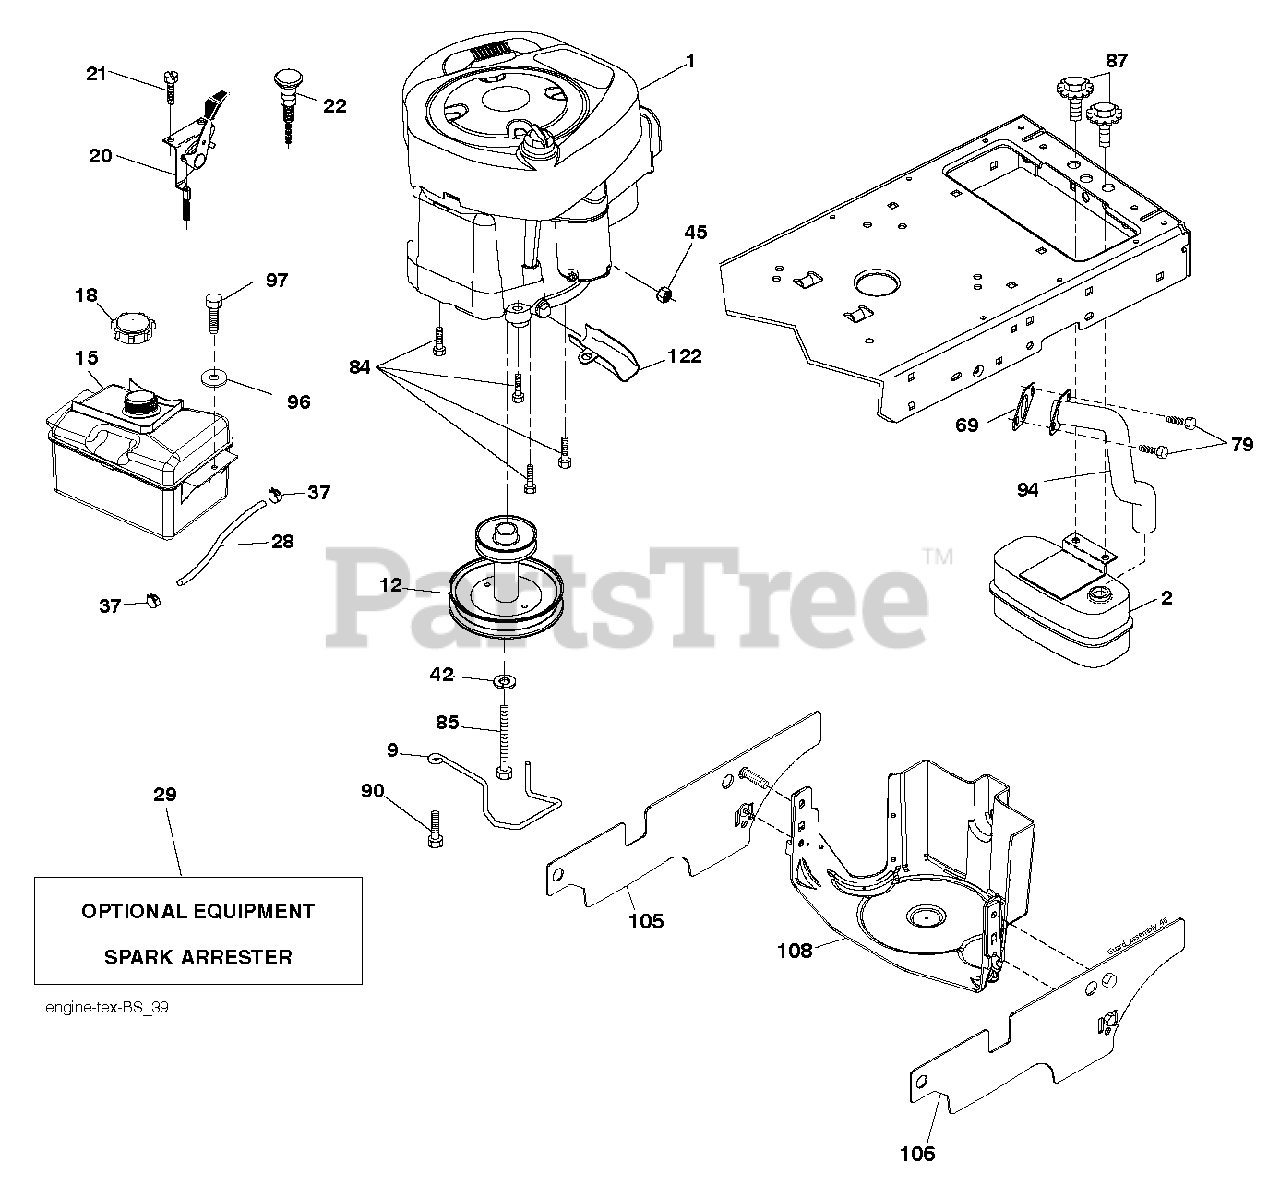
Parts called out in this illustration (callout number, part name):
2	MUFFLER.SINGLE.CYL.KOHL/B&S
9	KEEPER.BELT.ENGINE.4.2
12	PULLY ENGINE
15	TANK FUEL FRT 1.5 GAL
18	CAP ASM.FUEL.2.25"FR.
20	CONTROL.TH/CK.C.
21	SCREW.#10 X 0.750.BOS THREAD
28	LINE.FUEL.20
29	ARRESTER SPARK (OPTIONAL)
37	HOSE CLAMP
42	LOCKWASHER
45	NUT
69	REPL BY 532 27 22-93
79	SCREW.SOCKET HD.5/16-1
84	SCREW.3/8-16
85	BOLT HEX 7/16-20X4-1/4"
87	BOLT, 5/16-18 X 1 3/4
90	SCREW 3/8-16X1
94	EXHAUST.TUBE.B&S.
97	SCREW HEXWSHR 1/4-20X3/4
122	EXTENSION DRAIN OIL
